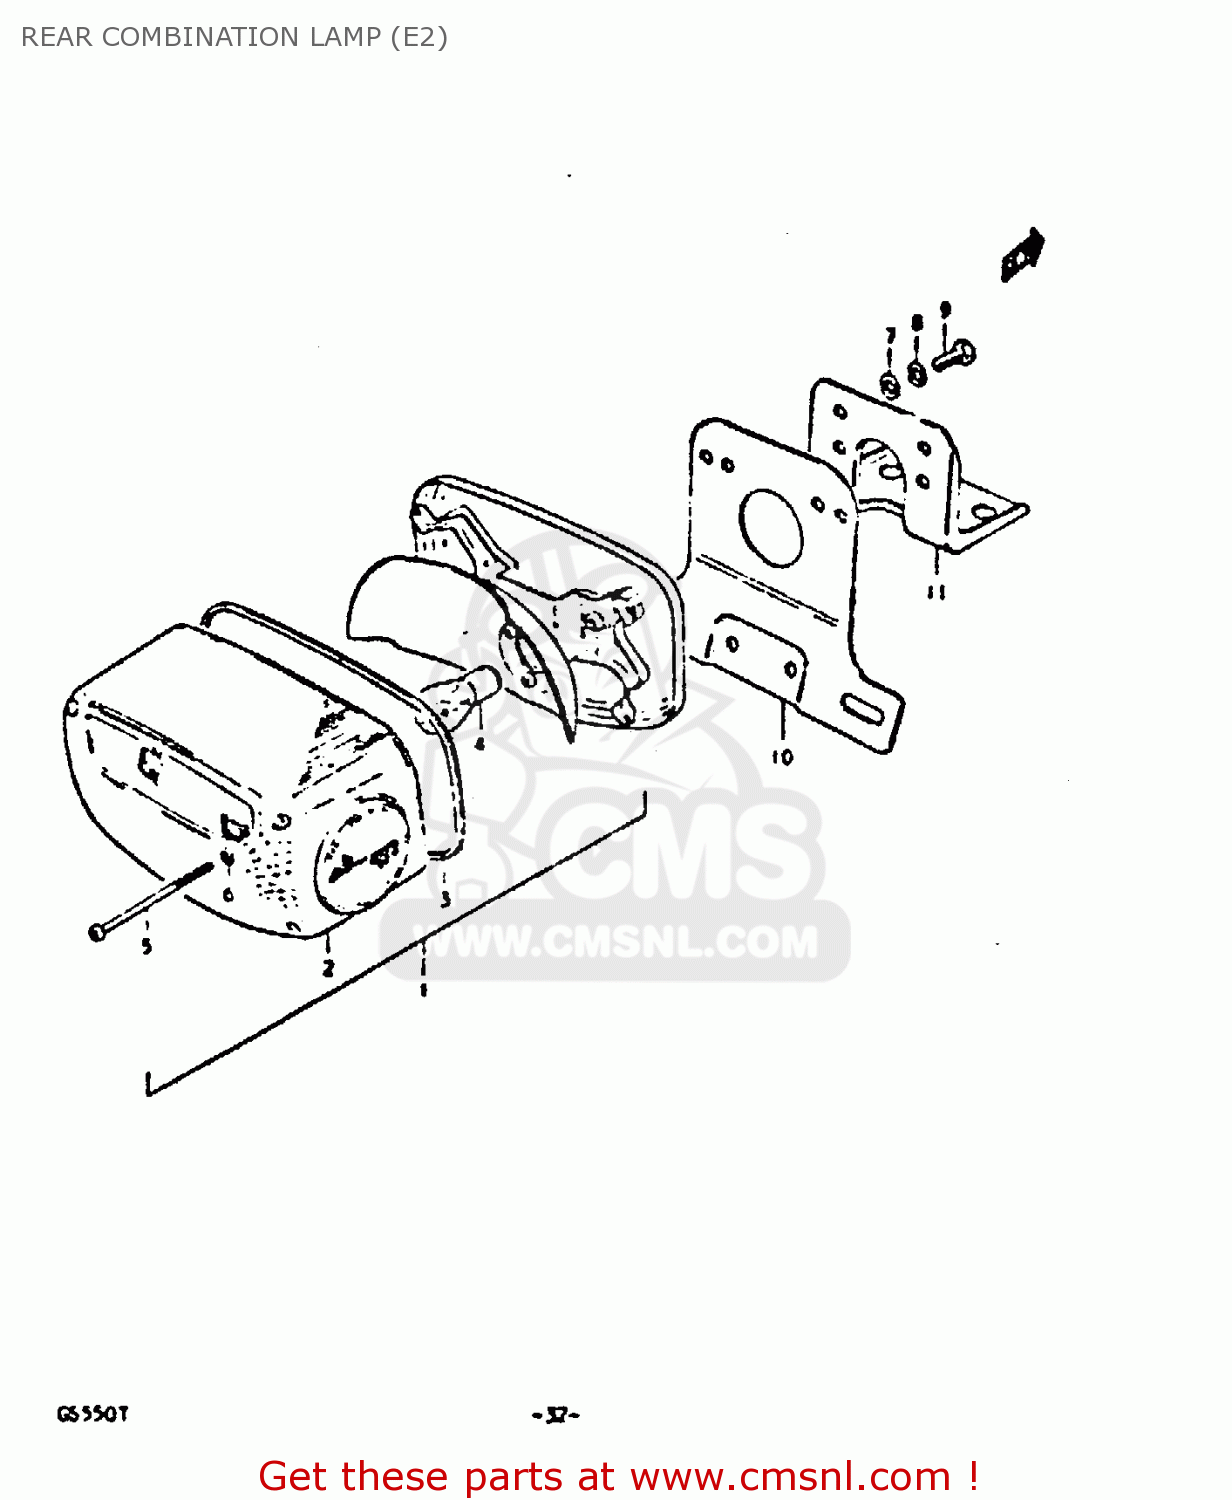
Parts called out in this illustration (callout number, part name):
1	LAMP ASSY, REAL COMBINATION
2	LENS,REAR COMBINATION LAMP
3	GASKET (NAS)
4	BULB
5	SCREW (4X55)
6	GASKET (NAS)
7	WASHER
8	LOCK WASHER
9	BOLT
10	BRACKET,LICENSE PLATE
11	BRACKET,LICENSE PLATE
